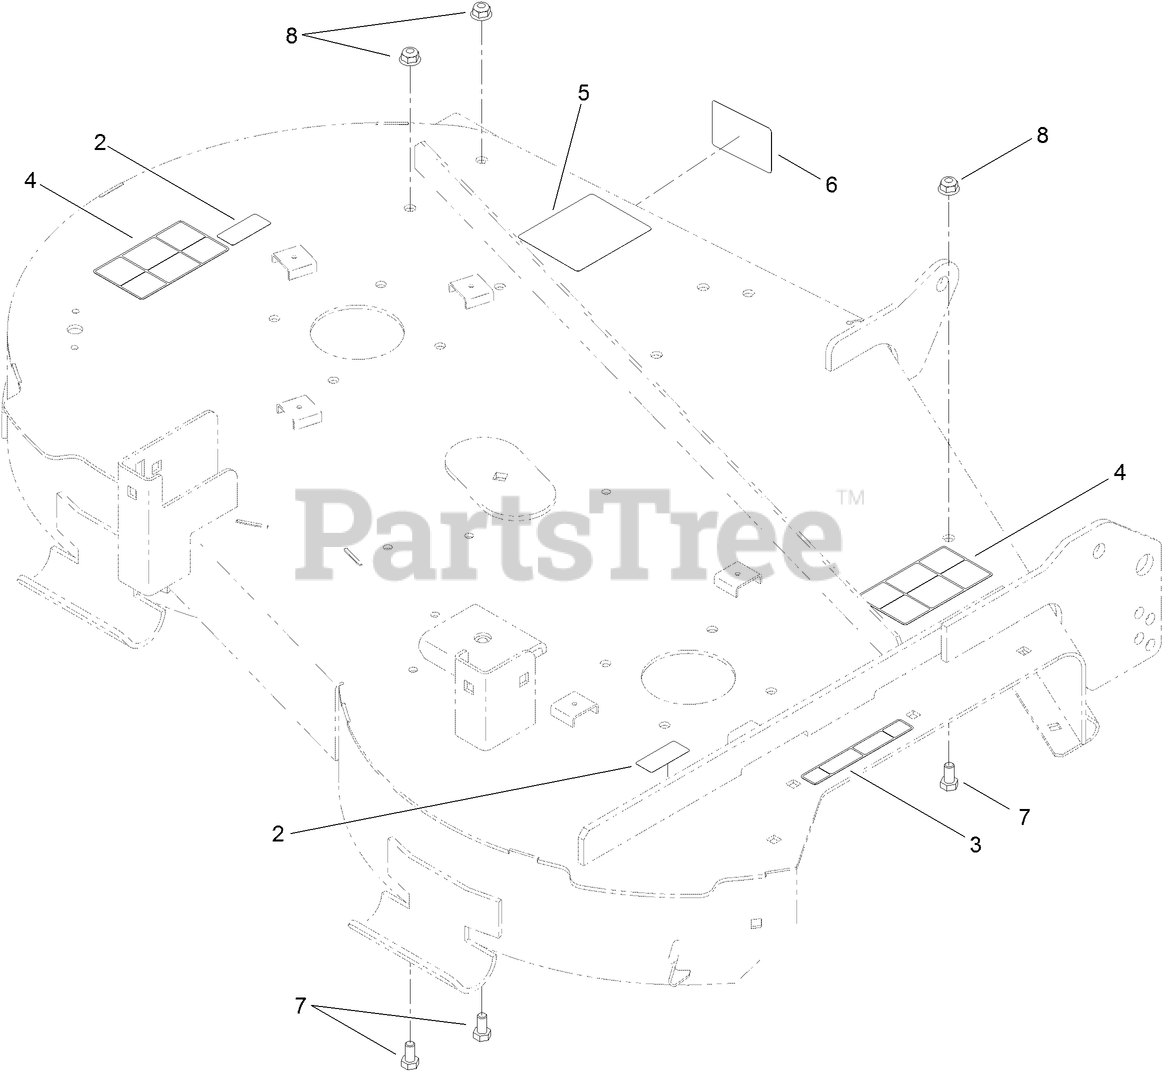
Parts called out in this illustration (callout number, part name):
2	DECAL-DANGER
3	DECAL-DANGER
4	DECAL-DANGER
5	DECAL-ROUTING, BELT
6	DECAL-SCALP, ANTI
7	SCREW-HH
8	NUT-HF, NI
